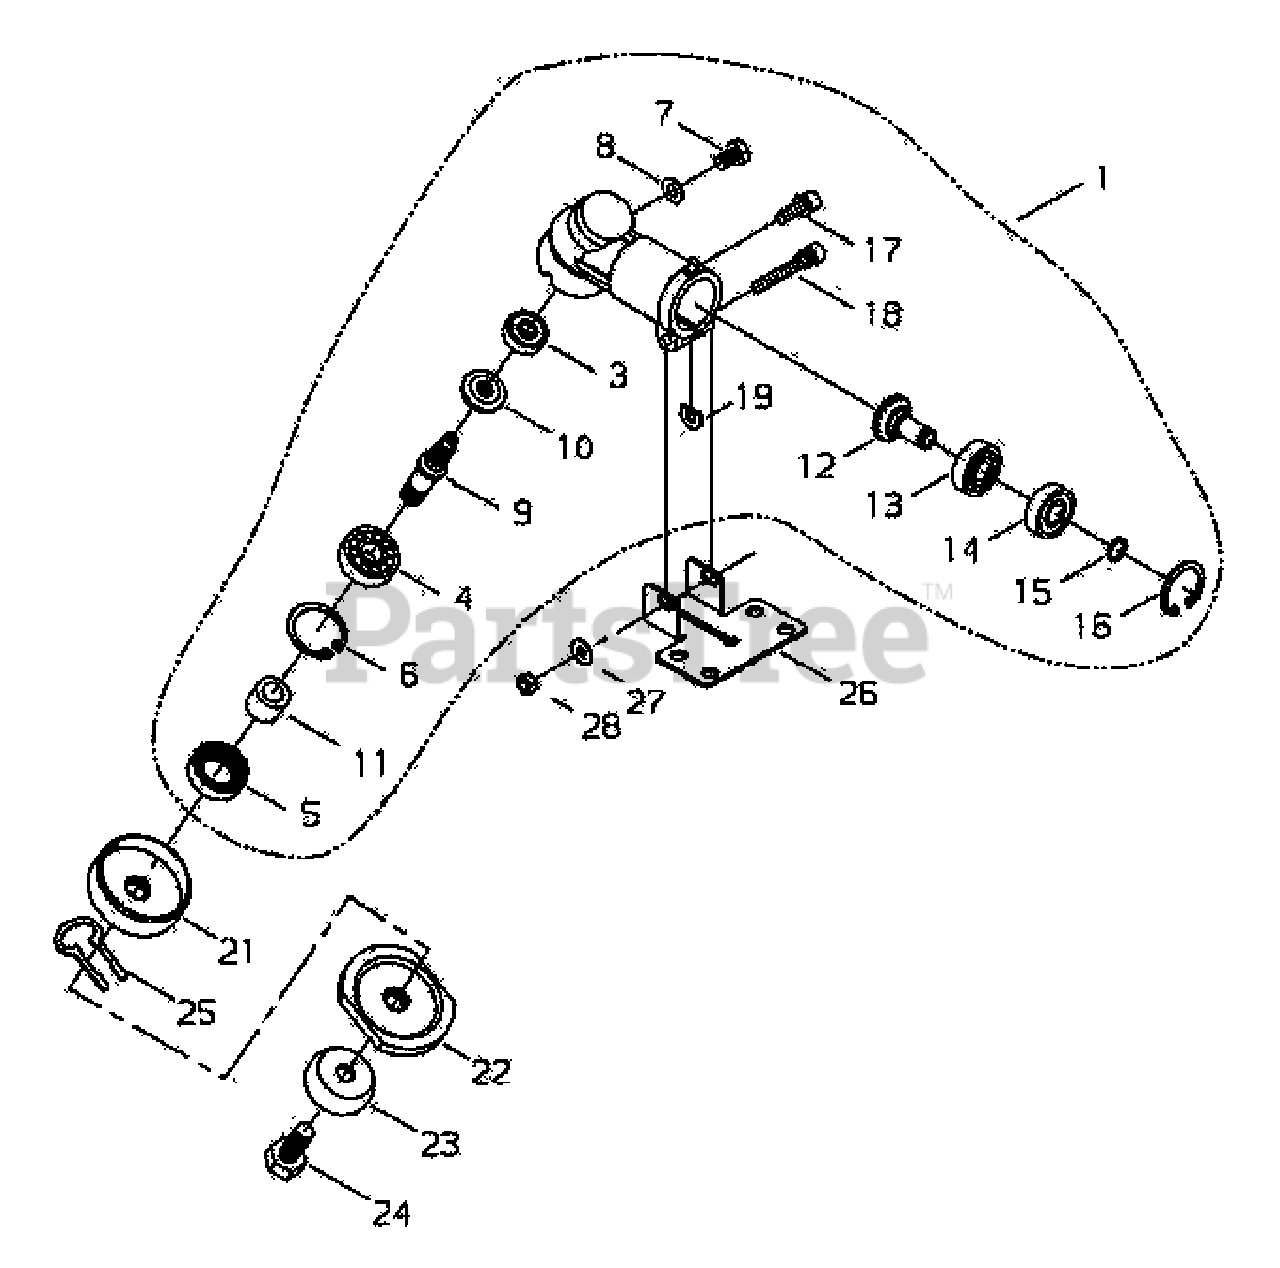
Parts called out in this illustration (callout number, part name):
1	GEAR CASE ASSY
3	BEARING, BALL - 626
4	BEARING, BALL - 6000
5	SEAL, OIL
6	RING, RETAINING - 26
7	BOLT - 6X10
8	WASHER
9	GEAR - SHAFT
10	GEAR - BEVEL
11	COLLAR
12	GEAR - SHAFT
13	BEARING, BALL - 608
14	BEARING, BALL - 608ZZ
15	RING, RETAINING
16	RING, RETAINING - 22
17	SCREW - 5X16
18	SCREW - 5X35
19	SHIM
21	HOLDER - A
22	HOLDER B, REPLACES 22035-13251, REPLACES 22553-13250
23	GUARD
24	BOLT - 7X18 -- LEFT HAND
25	SLIDE CLIP
26	CLAMP - LOWER
27	WASHER - 5
